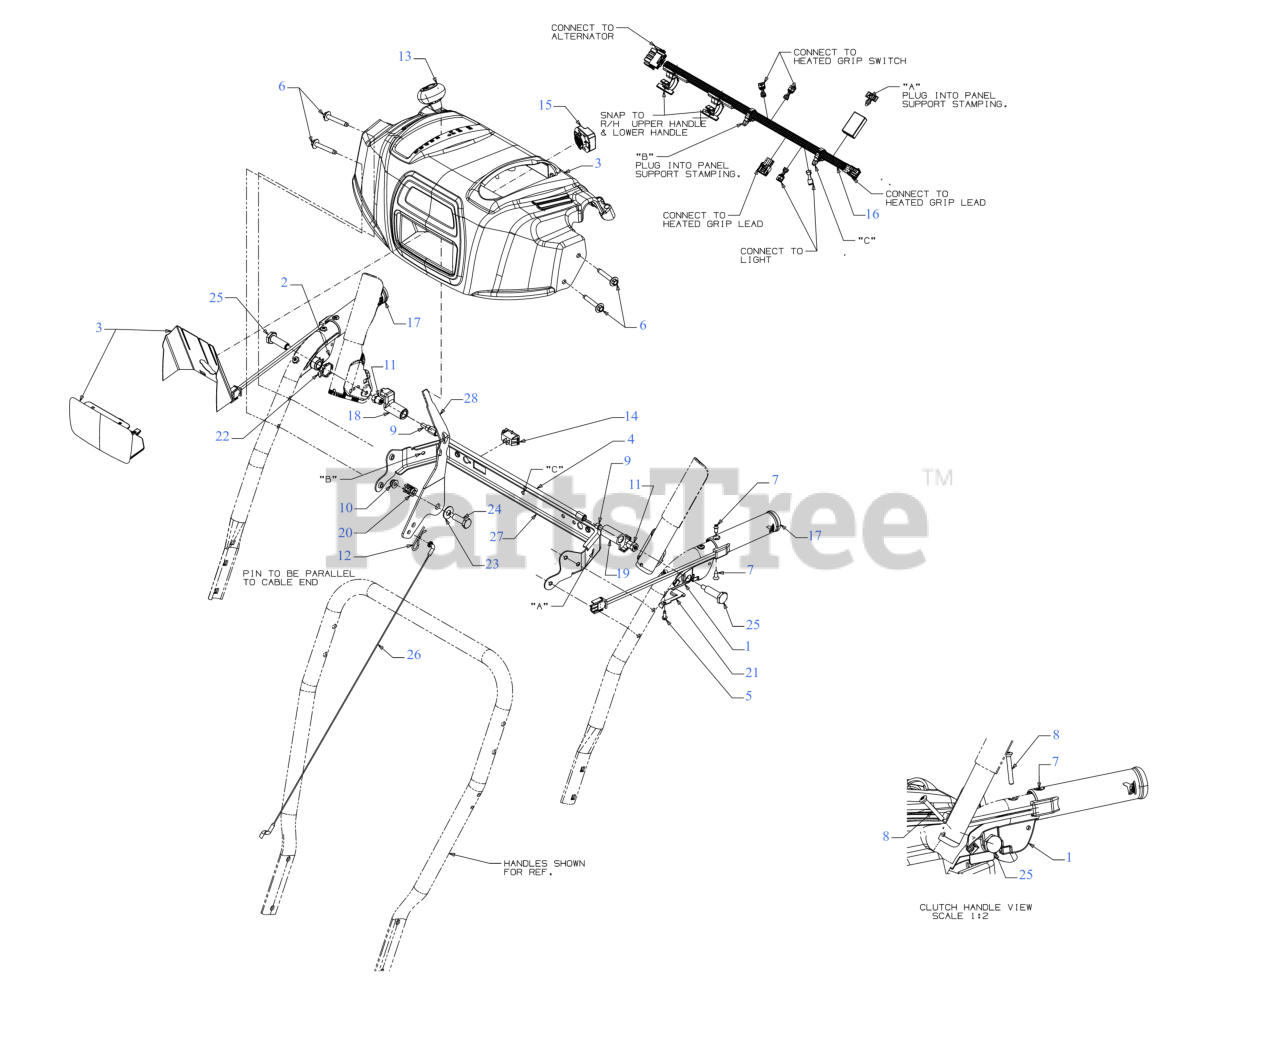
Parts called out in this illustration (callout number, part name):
1	CLUTCH LOCK HANDLE ASSEMBLY (LH)
2	CLUTCH LOCK HANDLE ASSEMBLY (RH)
3	HANDLE PANEL ASSEMBLY
4	PIVOT ROD
5	SCREW #8-16 x .50
6	SCREW 1/4-20 x 1.625
7	SCREW-AB #12-24 x .625
8	SCREW #10-24 x 1.375
9	SCREW 1/4-20 x .50
10	FLANGE LOCK NUT
11	HEX NUT W/PATCH
12	INTERNAL COTTER PIN
13	SHIFT KNOB
14	HEATED GRIP SWITCH
15	LED HEADLIGHT SOCKET (150 LUMNES)
16	HEATED GRIPS HARNESS
17	HEATED GRIP
18	LOCK PLATE
19	CLUTCH LOCK CAM
20	COMPRESSION SPRING
21	CLUTCH SPRING
22	TORSION SPRING
23	FLAT WASHER .40X.88X.060
24	SHOULDER SCREW
25	SHOULDER SCREW .437 x 1.345 1/4-20
26	SPEED SELECTOR CABLE (PLASTIC)
27	HANDLE SUPPORT BRACKET (POWDER BLACK)
